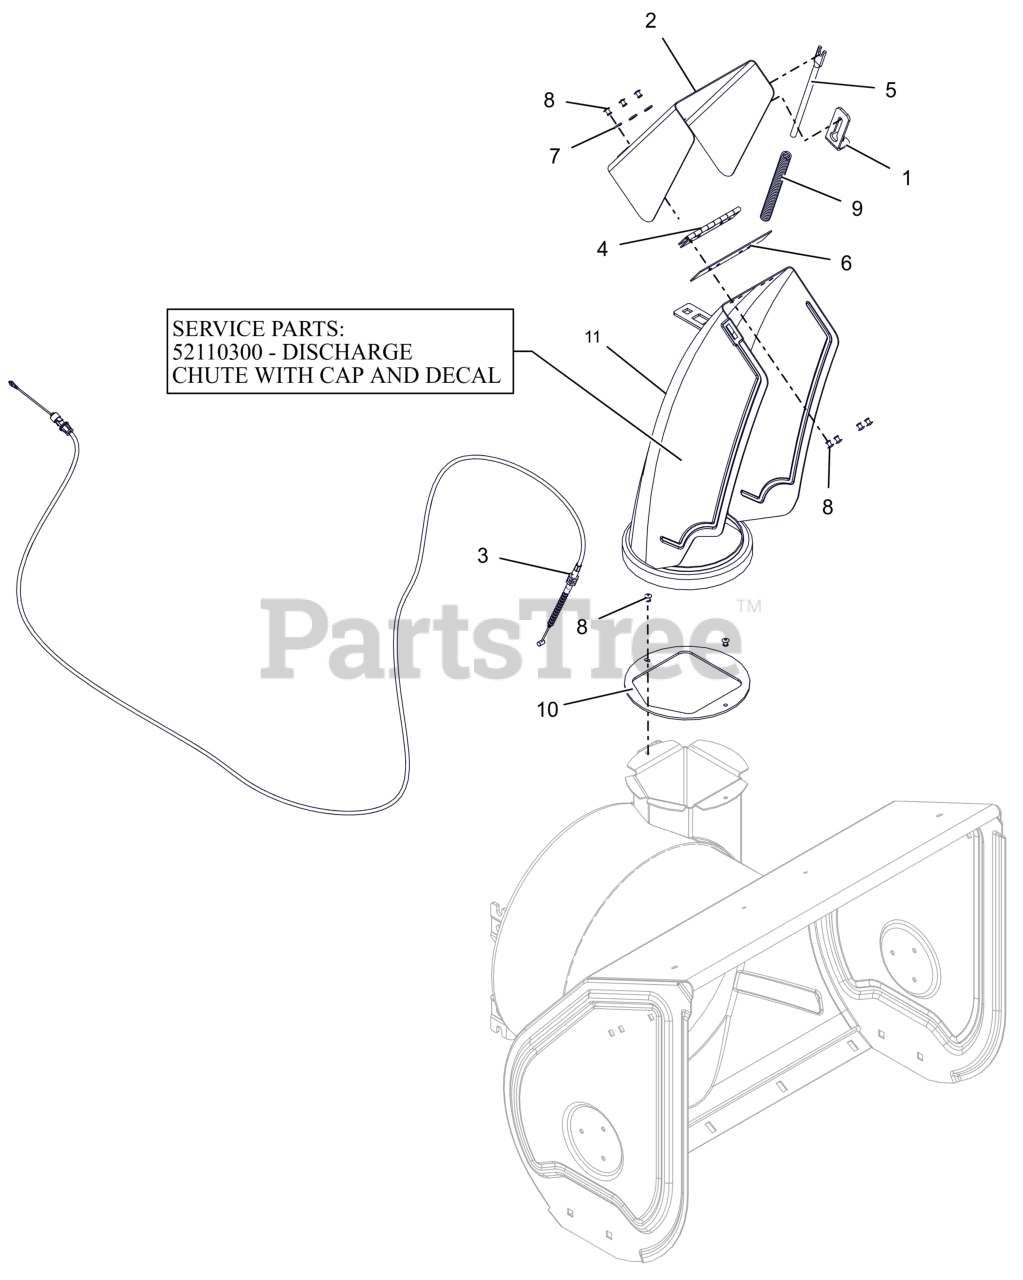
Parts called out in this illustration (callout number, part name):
1	BRACKET, ANCHOR-CHUTE CABLE
2	CAP, LARGE REMOTE W/DECAL
3	CABLE, DEFLECTOR - DELUXE
5	ROD, DEFLECTOR CAP
6	CAP SEAL 5.50
7	WSHR,FLT .196X.500X.066 ZCC
8	RVT, POP .1875 ZCC
9	SG-COMP .08X.40X6.50 14#/IN
10	BAFFLE, DISCHARGE NECK
11	CHUTE,DISCHARGE,RMT,ID
11	CHUTE, DISCHARGE W/CAP
